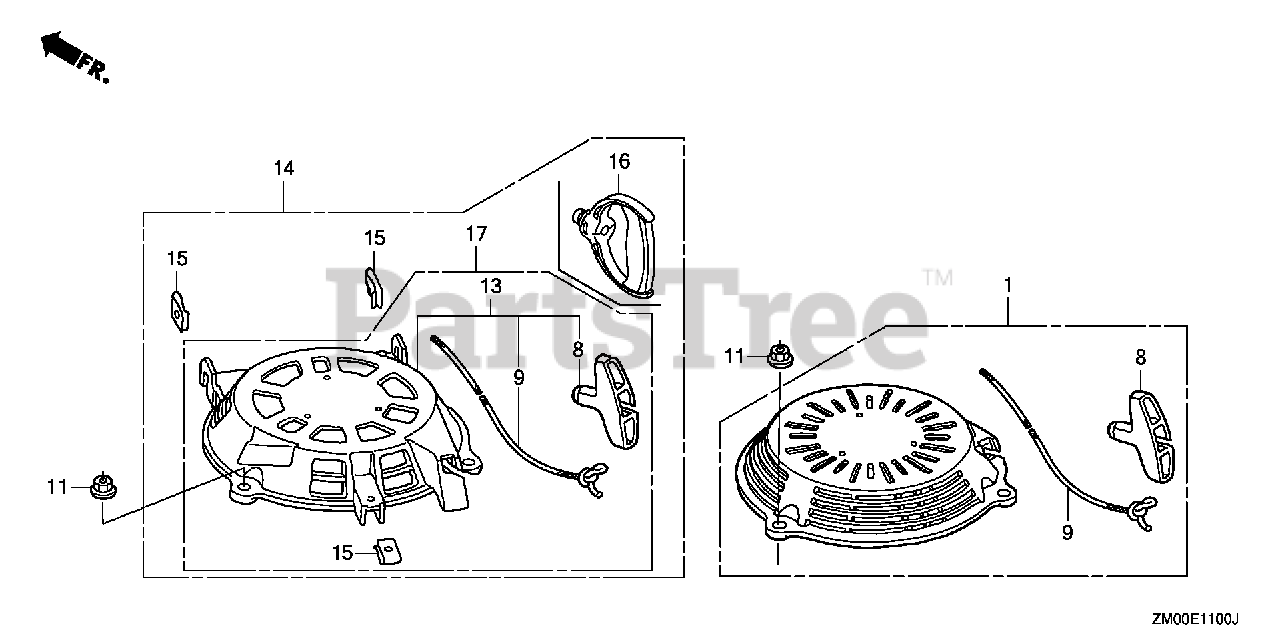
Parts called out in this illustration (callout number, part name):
1	STARTER ASSY., RECOIL *NH1* (LONG ROPE) (BLACK)
8	GRIP, STARTER
9	ROPE, RECOIL STARTER (LONG TYPE)
11	NUT, FLANGE (6MM)
